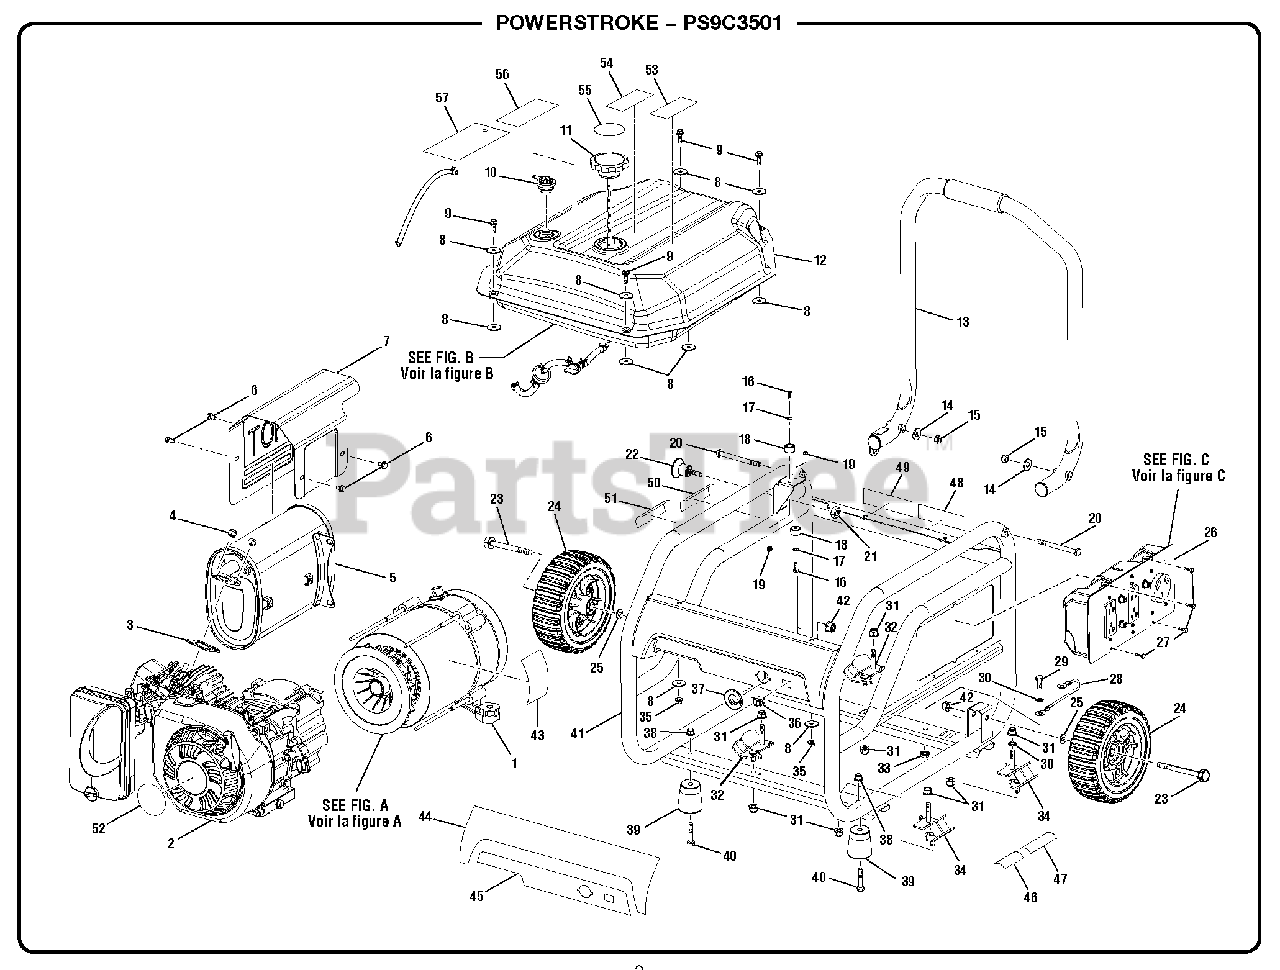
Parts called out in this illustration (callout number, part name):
1	Generator Head Assembly
2	Engine (212 cc)
3	Muffler Gasket
4	Lock Nut (M8)
6	Bolt (M6 x 10 mm)
7	Heat Shield
8	Washer (M8)
9	Bolt (M6 x 1 in., Hex Hd.)
10	Fuel Tank Vapor Vent
11	Fuel Cap Assembly
12	Fuel Tank Assembly
13	Handle Assembly
14	Washer (5/16 in.)
15	Lock Nut (5/16-18, Hex Hd.)
16	Bolt (M4 x 12.5 mm, Hex Hd.)
17	Washer (M4)
18	Rubber Bumper
19	Flange Nut (M4)
20	Pivot Pin (Handle)
21	Hex Nut (1/2-20)
22	Quick Release Pin
23	Axle Bolt (M10 x 1-1/4 in., Hex Hd.)
25	Washer (M10)
26	Control Panel Assembly
27	Screw (6-20 x 3/8 in., Type B)
28	Ground Wire Assembly
29	Bolt (5/16-18 x 3/4 in.)
30	Star Washer (5/16 in.)
31	Lock Nut (M8)
32	Isolator (Left)
33	Hex Nut (5/16-18)
34	Isolator (Right)
35	Flange Nut (M6)
36	Stop Switch
37	Fuel Valve Bezel
38	Lock Nut (M8)
40	Bolt (M8 x 45 mm, Flange Hex Hd.)
41	Carrier Assembly
42	Lock Nut (M10)
43	Data Label
44	Logo Label
45	Start Label
46	Inquires Label
47	Lubricant Label
48	Ground Warning Label
49	Fire Danger Label
50	Hot Surface Label
51	Combustion Label
52	Recoil Label
53	CPSC Label
54	E-85 Label
55	Fuel Stabilizer Label
56	Danger Label
57	Warning Hangtag
